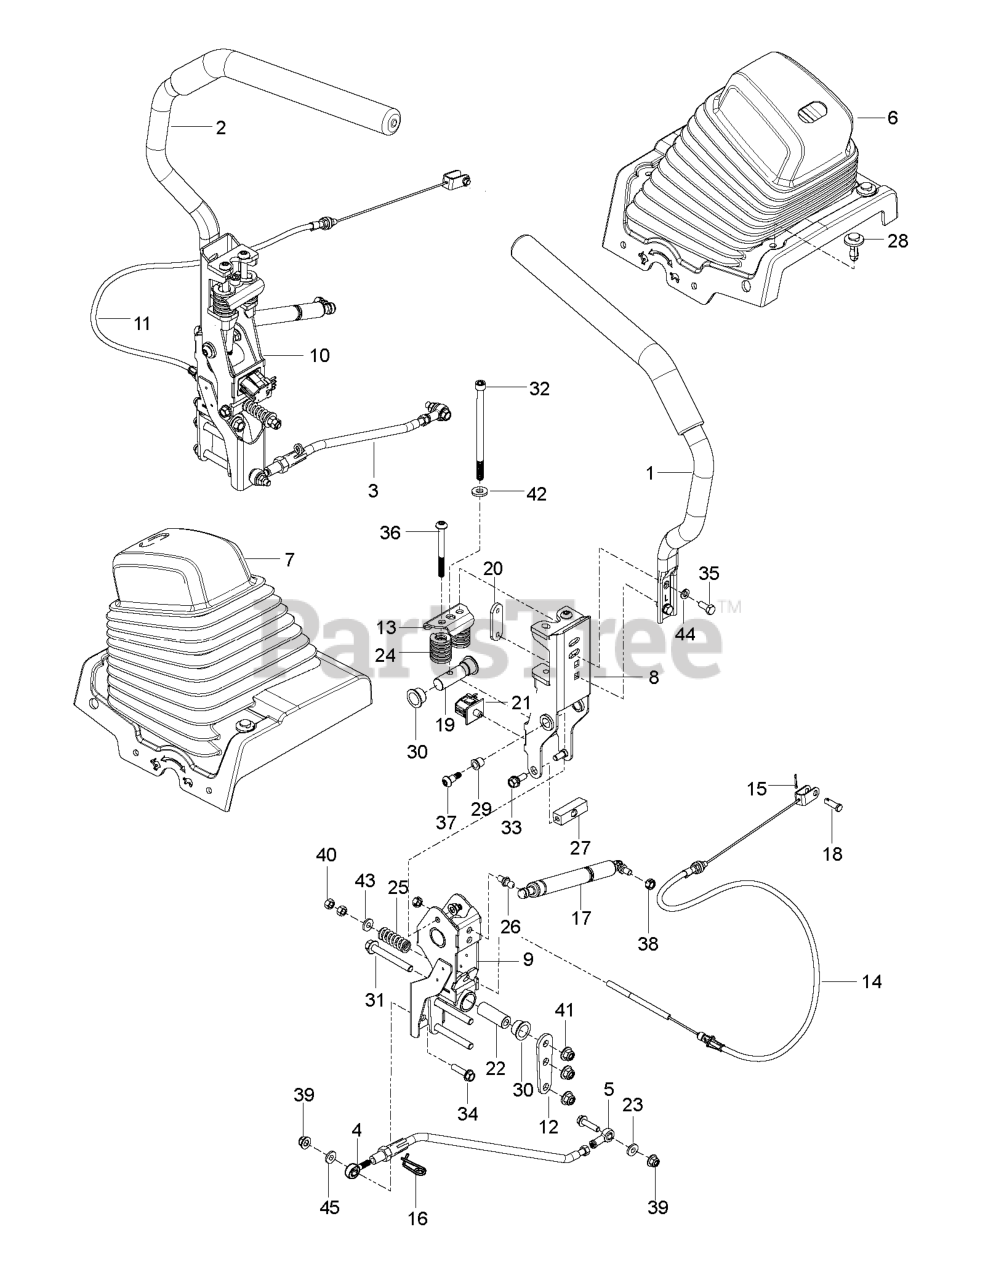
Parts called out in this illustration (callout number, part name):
1	LEVER.ASM.DRIVE.LH
2	LEVER.ASM.DRIVE.RH
3	CONTROL ROD COUPLER KIT
3	Rods
4	ROD.END.MALE.LH.THREAD
5	JOINT.HEIM.FEML.5/16.RH.THREAD
6	KIT.SERVICE.LEVER.BELLOW.LH
7	KIT.SERVICE.LEVER.BELLOW.RH
8	KIT.CARRIER.UPPR.W/BUSHINGS.RT
8	KIT.CARRIER.UPPR.W/BUSHINGS.LT
9	CARRIER.PNT.WLDMT.LOWER.EDIP
10	KIT.CONTROL.MECHANISM.LEFT
10	KIT.CONTROL.MECHANISM.RIGHT
11	KIT.CABLE.BRAKE.PARKING.LEFT
12	BRACKET.PNT.CONTROLS.MTG.EDIP
13	BRACKET.RETAINING.SPRING
14	CABLE.BRAKE.PARK
15	PIN COTTER;LOCKING;BOWTIE;1IN
16	CLIP.RETAINER.CONTROLS
18	PIN.CLEVIS.5/16.DIA.3/4.USABLE
21	SWITCH.SNPMNT.DELTA.NCNC.PZREF
22	SPACER.PIVOT
23	SPACER.7_16OD;5_16ID;STEP.UP
24	SPRING 1.25"ODX1.5"L
25	SPRING, BRAKE ROD
26	STUD.BALL.10MM
27	CABLE.YOKE.PARK.BRAKE
28	RIVET.PUSH.PIN.0.25IN.HOLE
29	BEARING.FLG.3/8.SHAFT.1/2.HSG
30	BEARING, FLANGE
31	HHFS 3/8-16 X 3 GRD 5 ZD
32	SCREW.SHCS.3/8-16 X 6L.ZY
33	BOLT, SHOULDER
34	HHFS 5/16-18 X 1.25 TPBLT GD 5
35	HCS 5/16C X 3/4
36	SCREW.SHCS.5/16-18 X 3-1/2"
37	SCREW.SHLDR.3/8 X 1/2.5/16-18
38	NUT 5/16C CENTERLOCK
39	5/16-18 NYLOC FLANGE NUT
41	NUT 3/8-16 HEX FLG NYLOC ZD
42	WASHER, 3/8 THICK
43	WASHER.5/16.FLAT.STE.STD.
44	WASHER.LOCK.HVY.HLCL.SPR.5/16
45	WASHER
